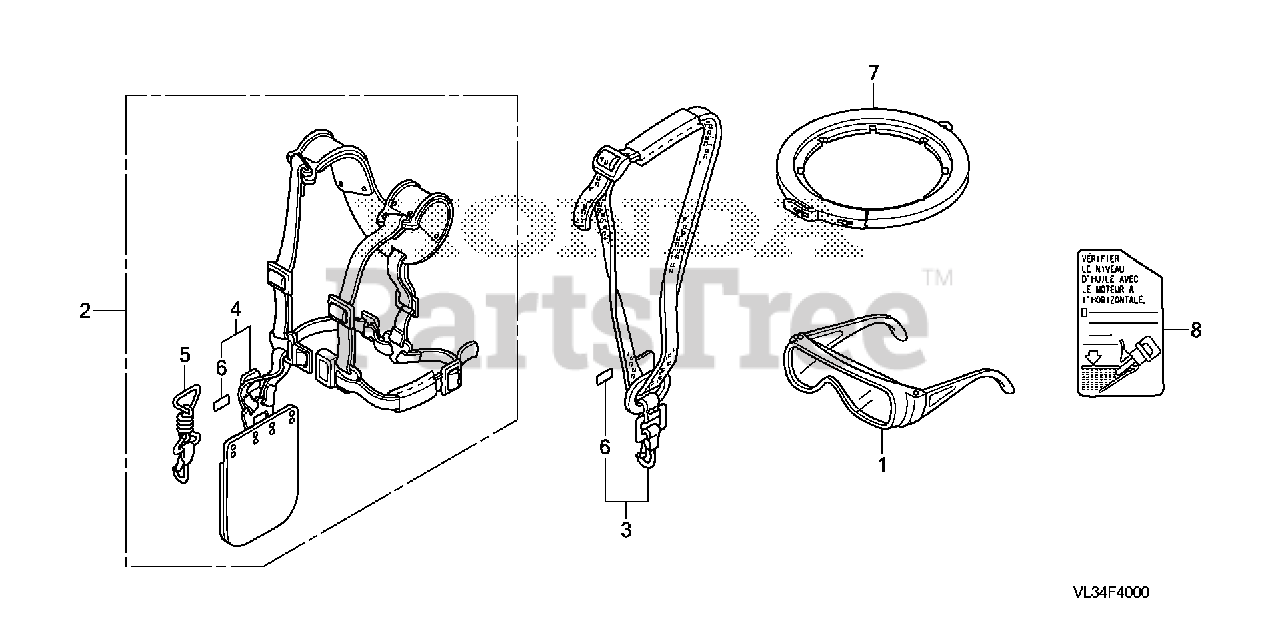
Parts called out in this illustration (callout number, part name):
1	PROTECTOR, EYE
2	BELT ASSY., SHOULDER
4	BELT, SHOULDER
5	HOOK, SHOULDER BELT
6	MARK, QUICK RELEASE (E)
7	COVER, BLADE
